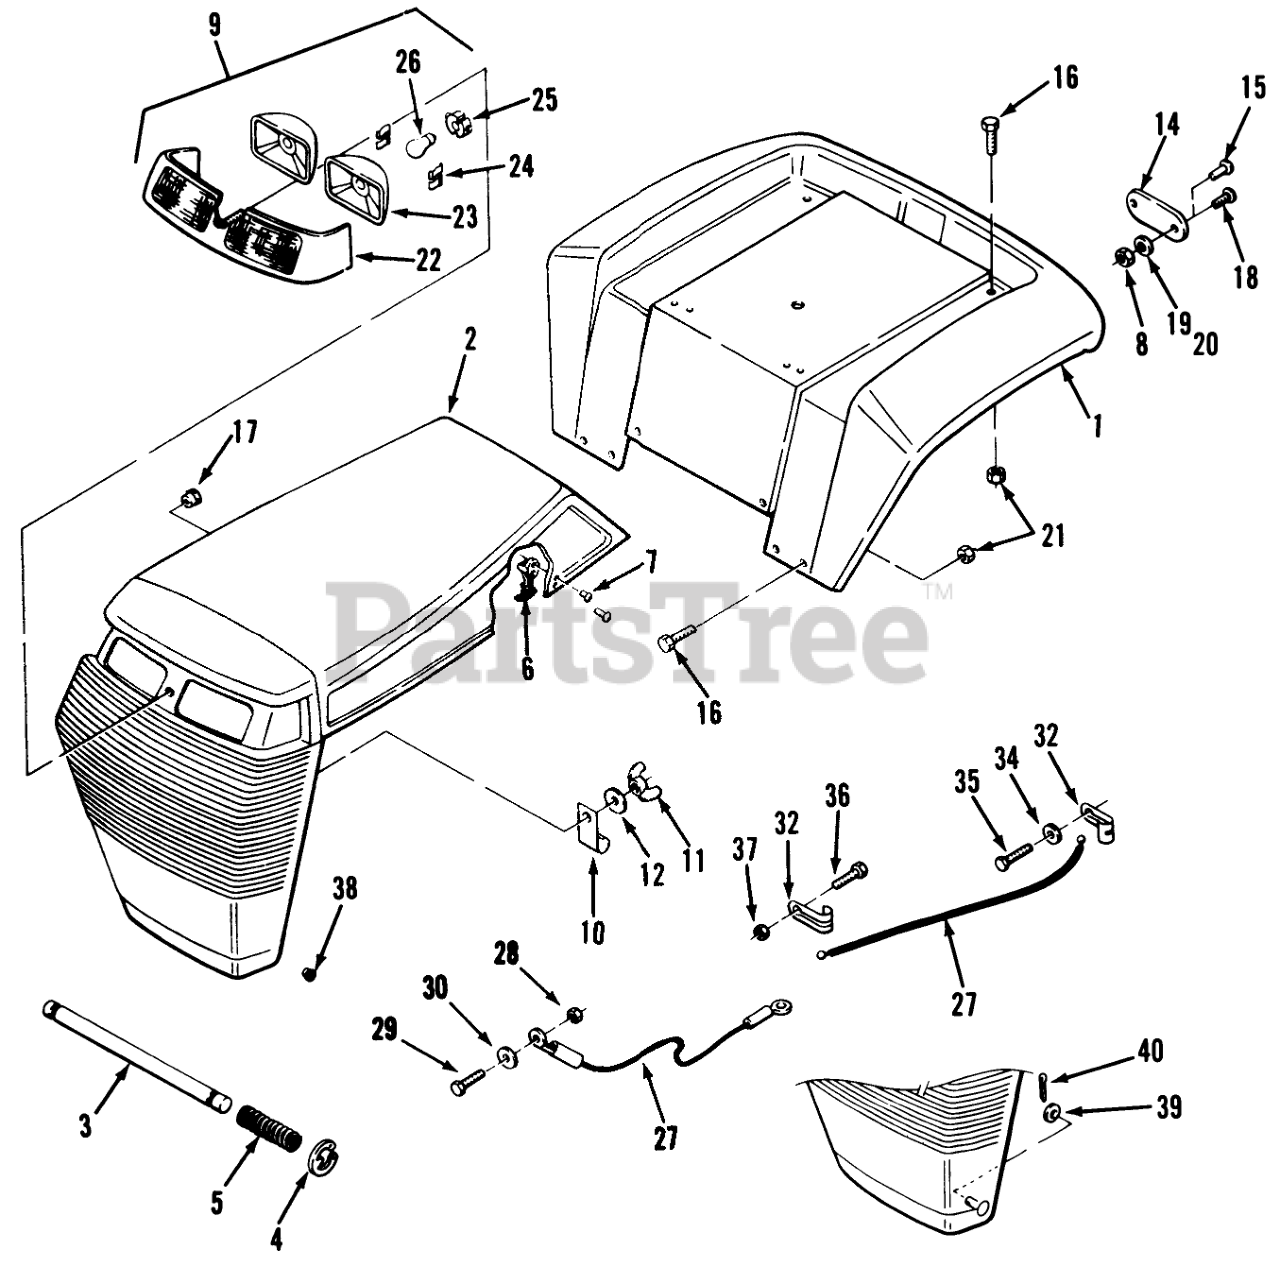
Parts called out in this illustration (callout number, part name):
1	FENDER R
2	Hood & Grill
4	E-Ring
5	SPRING
6	HANDLE ASM
7	RIVET-POP
8	Nut
9	Head Light Bar (Includes items 22, 23, 24 & 2] of 26)
10	J-CLIP
11	Nut-Wing
12	WASHER
14	Reflector
15	Poprivet
16	Bolt-Carriage
17	BUSHING-NYLON 1.093
18	Screw
19	WASHER
20	Lockwasher
21	Nut
21	Washer-Lock
22	LIGHT-BAR BLACK
23	LIGHT POD
24	RETAINER
25	SOCKET-HEADLIGHT
26	BULB
27	Hood Lanyard Cable
28	E.S. Nut #10-24
29	Screw-Machine
30	WASHER-BACKING
32	CLEVIS
34	Washer
35	Bolt
36	Screw-Machine
37	Nut
38	NYLINER BUSHING
39	WASHER 5/16 SAE
40	Cotter Pin
